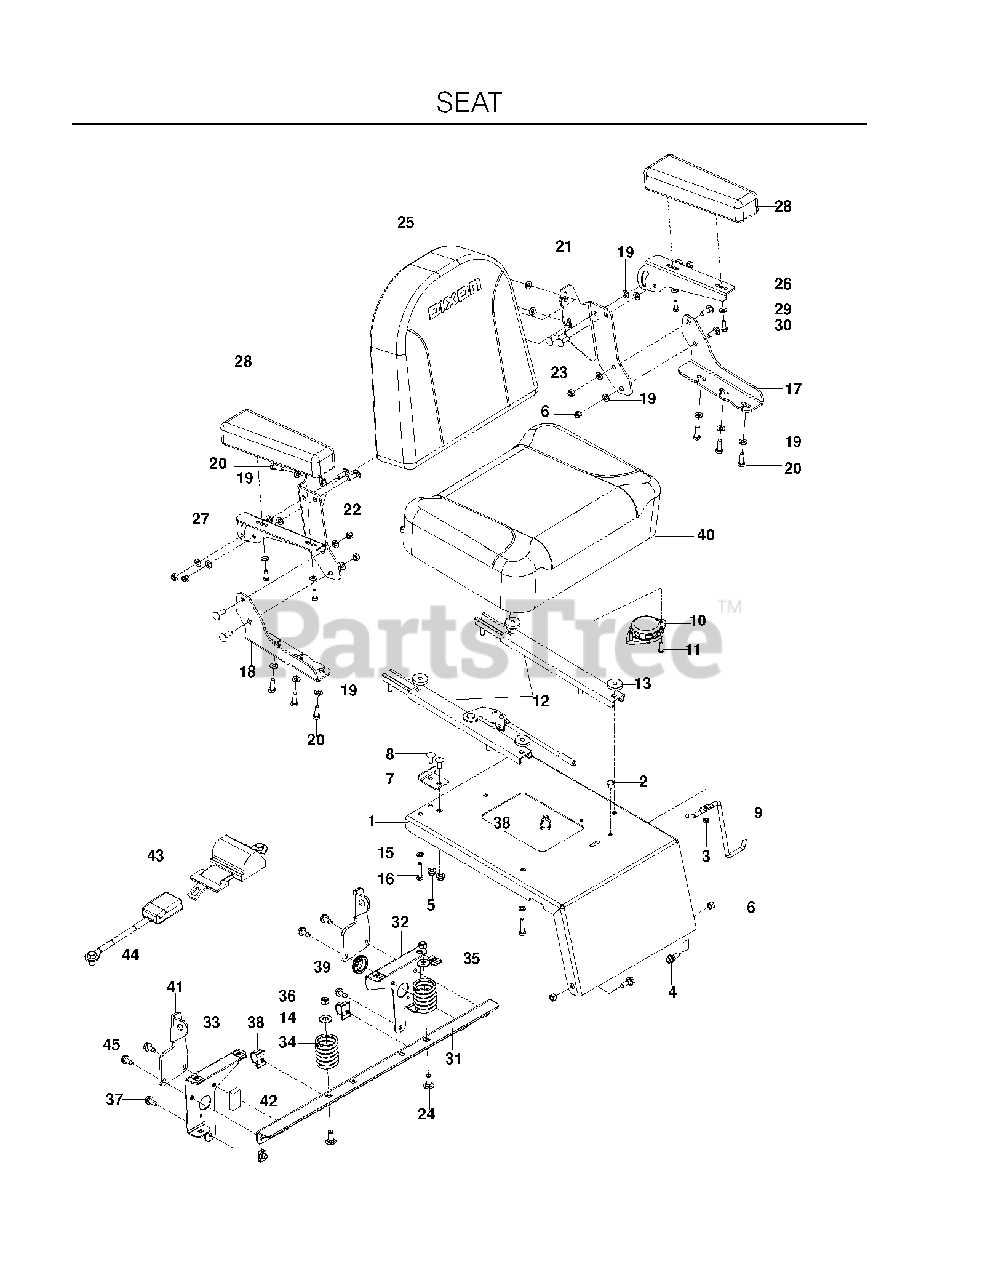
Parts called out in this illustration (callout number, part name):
1	SEAT MOUNT, W/DECALS
2	RHSNB 1/4C X 3/4
3	NUT 1/4-20 NYLOC
4	SB 5/16-18 HEX HD GD5, BLK ZN
5	5/16-18 NYLOC FLANGE NUT
6	NUT 5/16 NYLOC
7	STOP, SEAT - BLACK
8	RHSNB 5/16-18 X 3/4
9	STOP, SEAT, FORWQARD
10	SEAT SWITCH MILSCO
11	SCR 1/4-20X3/4 SLTD RDHD GR2ZD
12	SEAT SLIDE (SET)
13	WASHER NYLON
14	WASHER 3/8 FLAT
15	WASHER 5/16 LOCK
16	5/16-18X1-1/2 HHB GR5WNY
17	SEAT BOTTOM BRKT LH
18	SEAT BOTTOM BRKT RH
19	FLAT WASHER 5/16 SAE
20	5/16-18X1 HHB G5W/NY
21	SEAT BACK BRKT LH
22	SEAT BACK BRKT RH
23	RHSNB 5/16C X 1
24	RHSNB 3/8C X 1
25	SEAT BACK
26	ARM REST BRACKET LH
27	ARM REST BRACKET RH
28	ARMREST
29	WASHER 1/4 SAE
30	HCS 1/4C X 3/4 HCS
31	SUPPORT, SEAT
32	SUPPORT, LT
33	SUPPORT, RT
34	SPRING, SEAT
35	U-CLIP 5/16-18 NUT RETAINER
36	NUT 3/8-16 NYLOC
37	BOLT 5/16-18 X 3/4
38	TIE WRAP, 8-3/8", W/CLIP
39	RUBBER GROMMET
40	SEAT BOTTOM
41	MOUNT, SEAT BELT, BLK
42	WEATHERSTRIPPING, 1/2 X 1
43	SEAT BELT - RETRACTABLE
44	HCS 7/16-20 X .75 GD 5
45	Hex Washer Head Bolt, 5/16-18 X 3/4 Thread Forming
